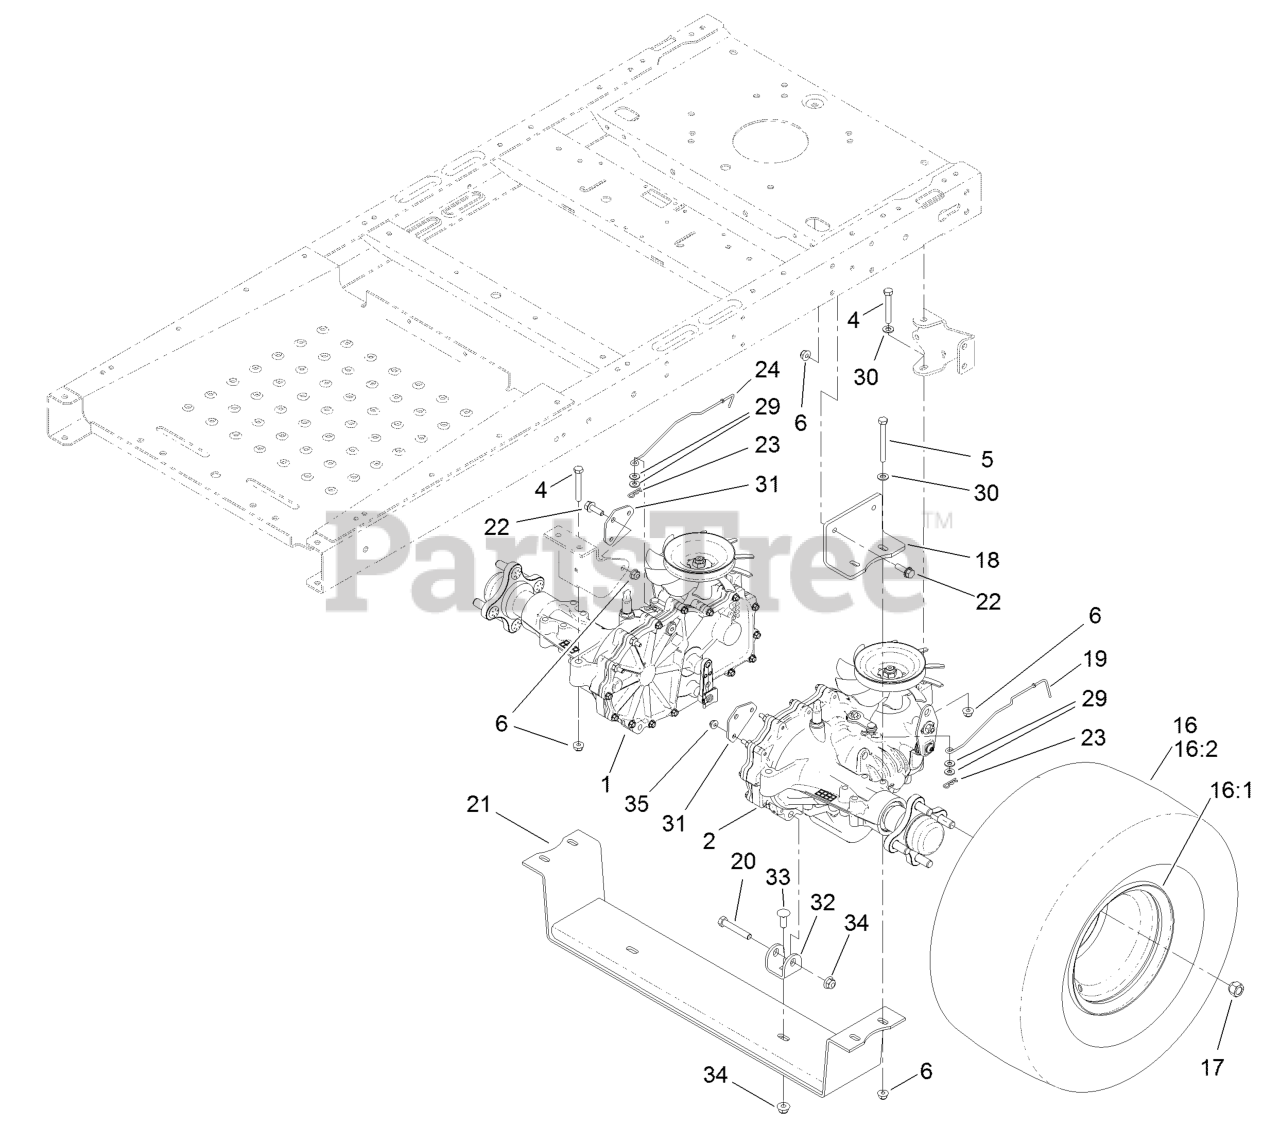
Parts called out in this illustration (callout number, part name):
1	RH HYDRO TRANSAXLE ASM
2	LH HYDRO TRANSAXLE ASM
4	SCREW-HH
5	SCREW-HH
6	NUT-HF, NI
16	WHEEL AND TIRE ASM
16:1	WHEEL,10 X 6.00
17	NUT-LUG
18	MOUNT-HYDRO
19	ROD-BYPASS, LH
20	SCREW-HH
21	MOUNT-HYDRO
22	SCREW-HHF
24	ROD-BYPASS, RH
29	WASHER-FLAT
30	WASHER-PLAIN
31	PLATE-HYDRO MOUNT
32	TAB-HYDRO
33	SCREW-CARR
34	NUT-HF, NI
